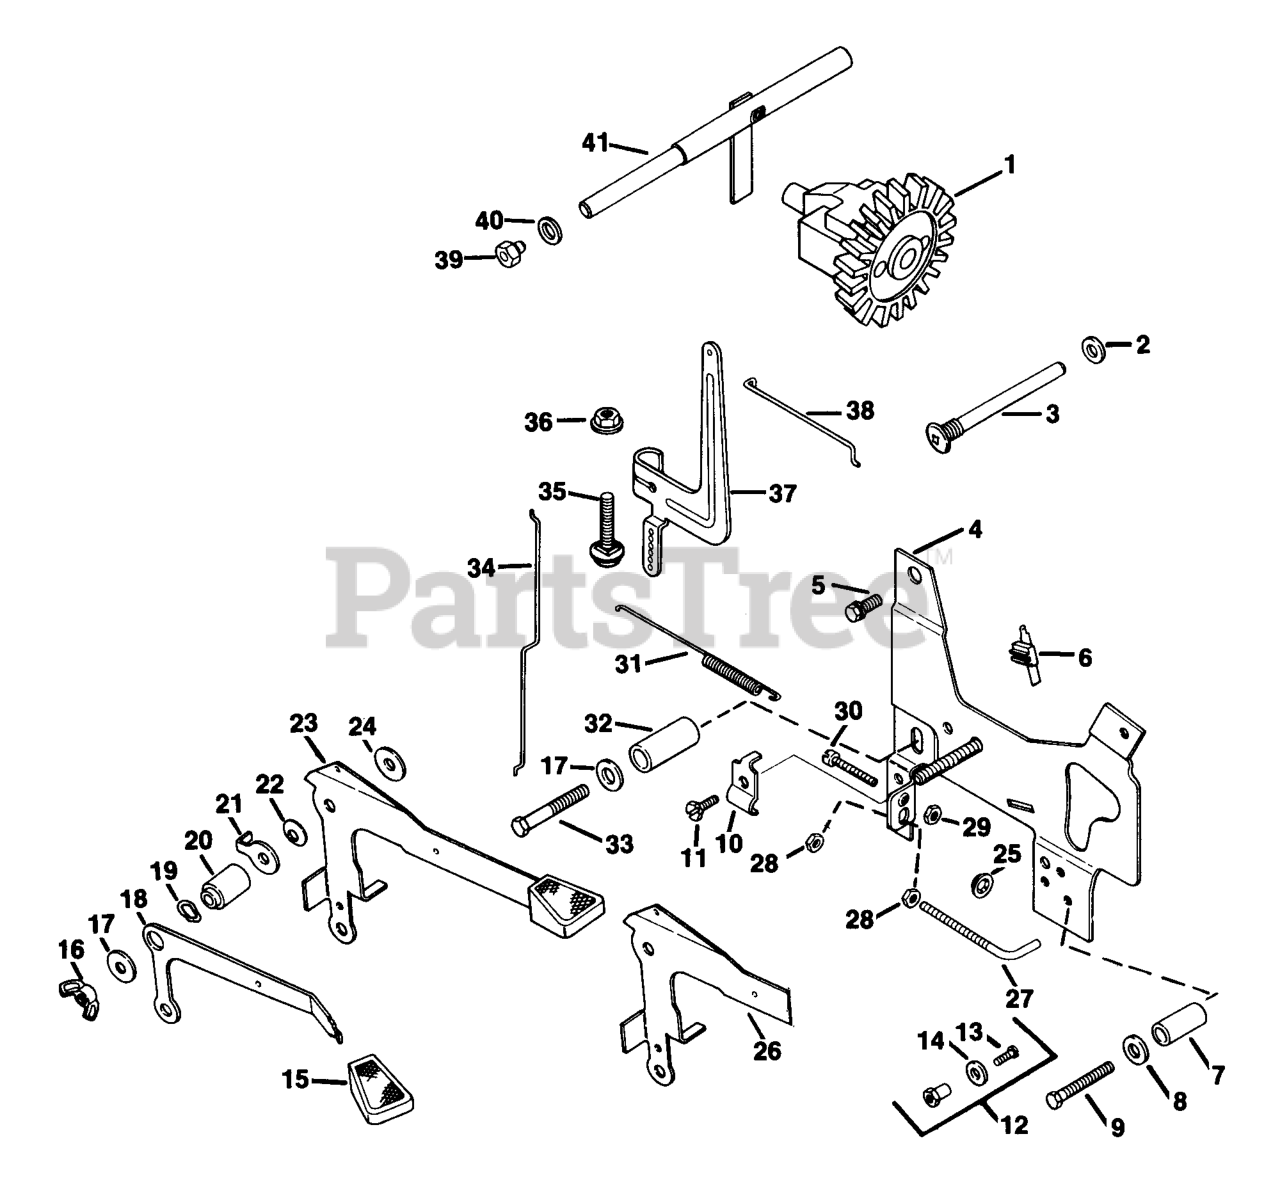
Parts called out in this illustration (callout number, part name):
1	KIT, GOVERNOR GEAR
4	BRACKET - USE 41 126 34
5	SCREW, SEMS 1/4-20-1/2"
6	SWITCH - USE 25 099 12
7	SPACER - USE 41 112 09
8	WASHER - USE X-25-92
9	SCREW, IND HD 10-24X1 3/8"
11	SCREW, IND SLT HD 10-24X3/8" USE 25 086 79-S
12	KIT, CLAMP
13	SCREW - USE 41 086 20
14	WASHER, FLAT 1/4"
15	KNOB - DISCONTINUED
16	NUT - USE X-101-8
17	WASHER, FLAT 1/4" (O.D. 5/8")
19	WASHER, SPRING 1/4"
21	TAB - USE 52 448 02
22	WASHER, SPRING 7/16" - DISCONTINUED
24	WASHER, FLAT 1/4"
26	LEVER - USE 41 090 18
29	NUT, MACH SCREW #8-32 GRD 2 USE 25 100 16-S
30	SCREW, SLT FLS 8-32X1"
31	KIT - USE 41 755 23
32	SPACER - USE 41 112 08
35	BOLT, RD HD SQ NCK 1/4-20X1"
36	PALNUT, 1/4-20
37	KIT - USE 41 755 23
38	LINKAGE
41	KIT,SHAFT
